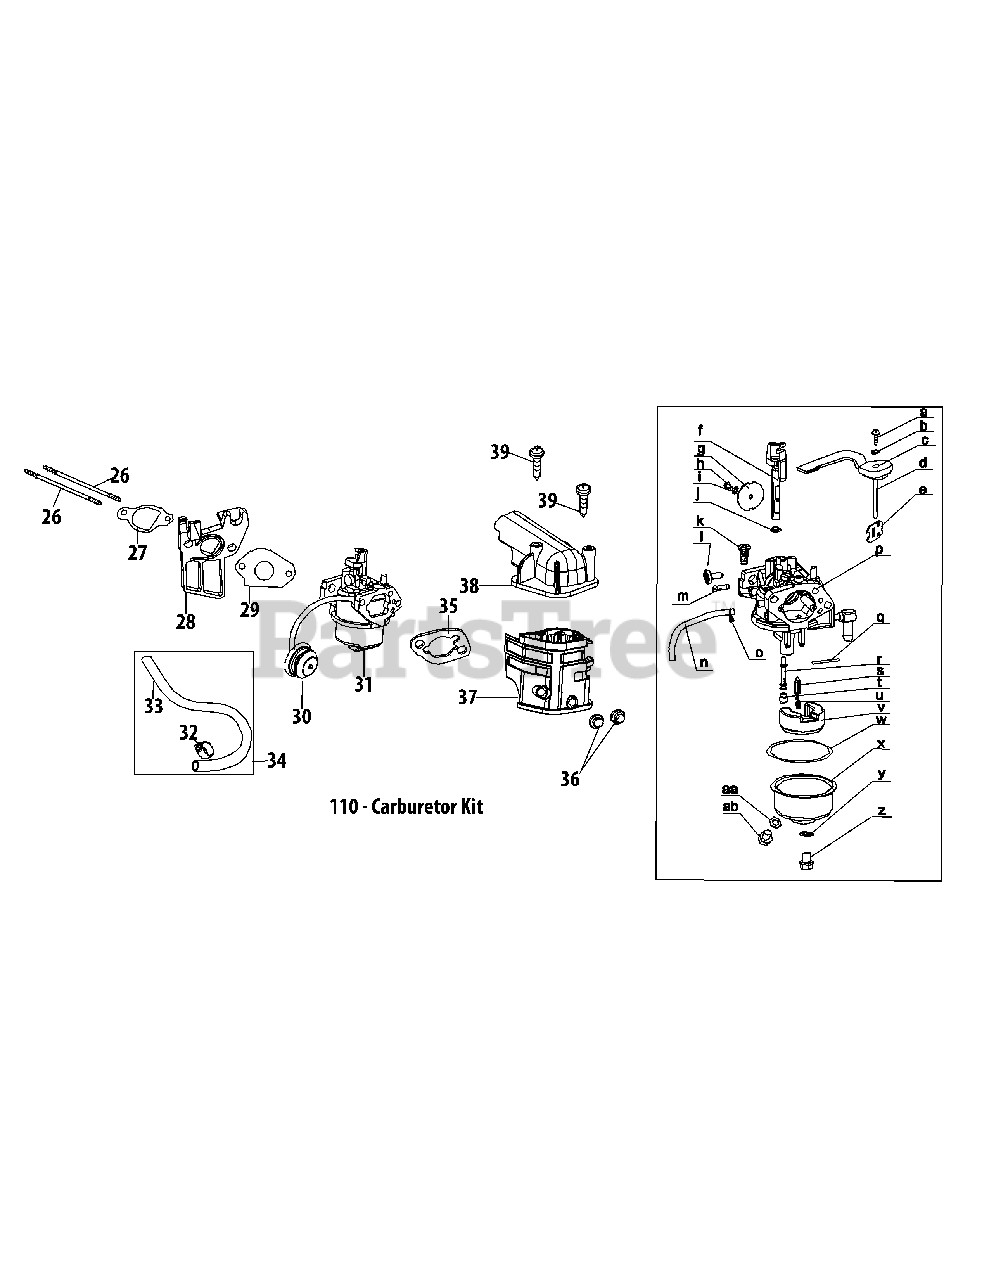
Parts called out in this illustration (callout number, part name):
26	Stud M6×110
27	Carburetor Insulator Gasket
28	Carburetor Insulator
29	Carburetor Gasket
30	Primer Assembly
31	Carburetor Assembly
32	Fuel Hose Clamp
33	Fuel Hose
34	Fuel Line Kit
35	Carburetor Gasket Plate
37	Air Cleaner Housing
38	Air Cleaner Assembly
39	Self-Tapping Bolt M4.2×45
110	Carburetor Kit
